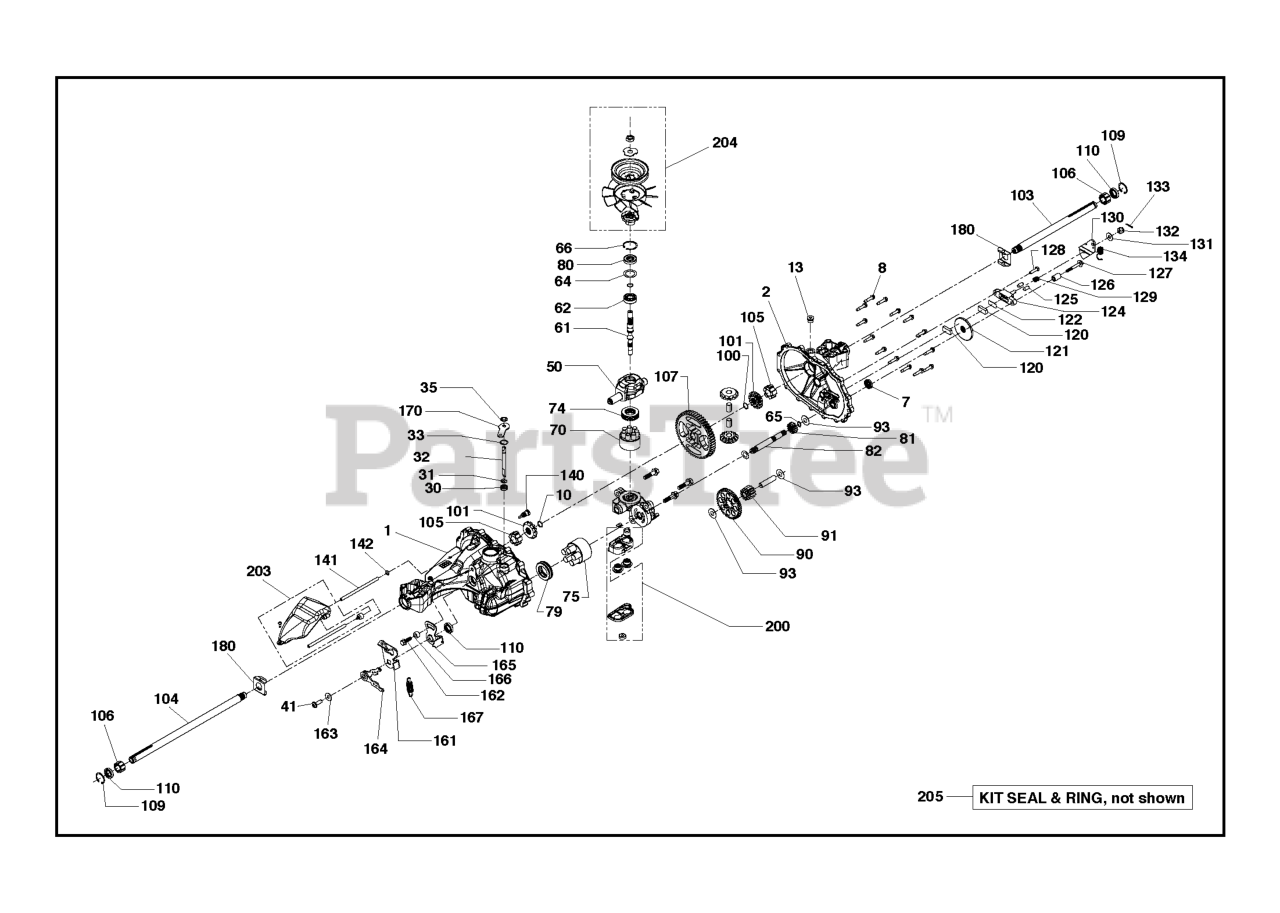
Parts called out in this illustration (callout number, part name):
62	BALL BEARING
75	KIT CYLINDER #70331
80	SEAL LIP
109	RETAINER.RING.INT.AXLE
122	PUCK PLATE 44134
125	BRAKE PIN 44127
128	BOLT W/NYLOCK 44433
163	WASHER FLAT
I3I	WASHER FLAT
